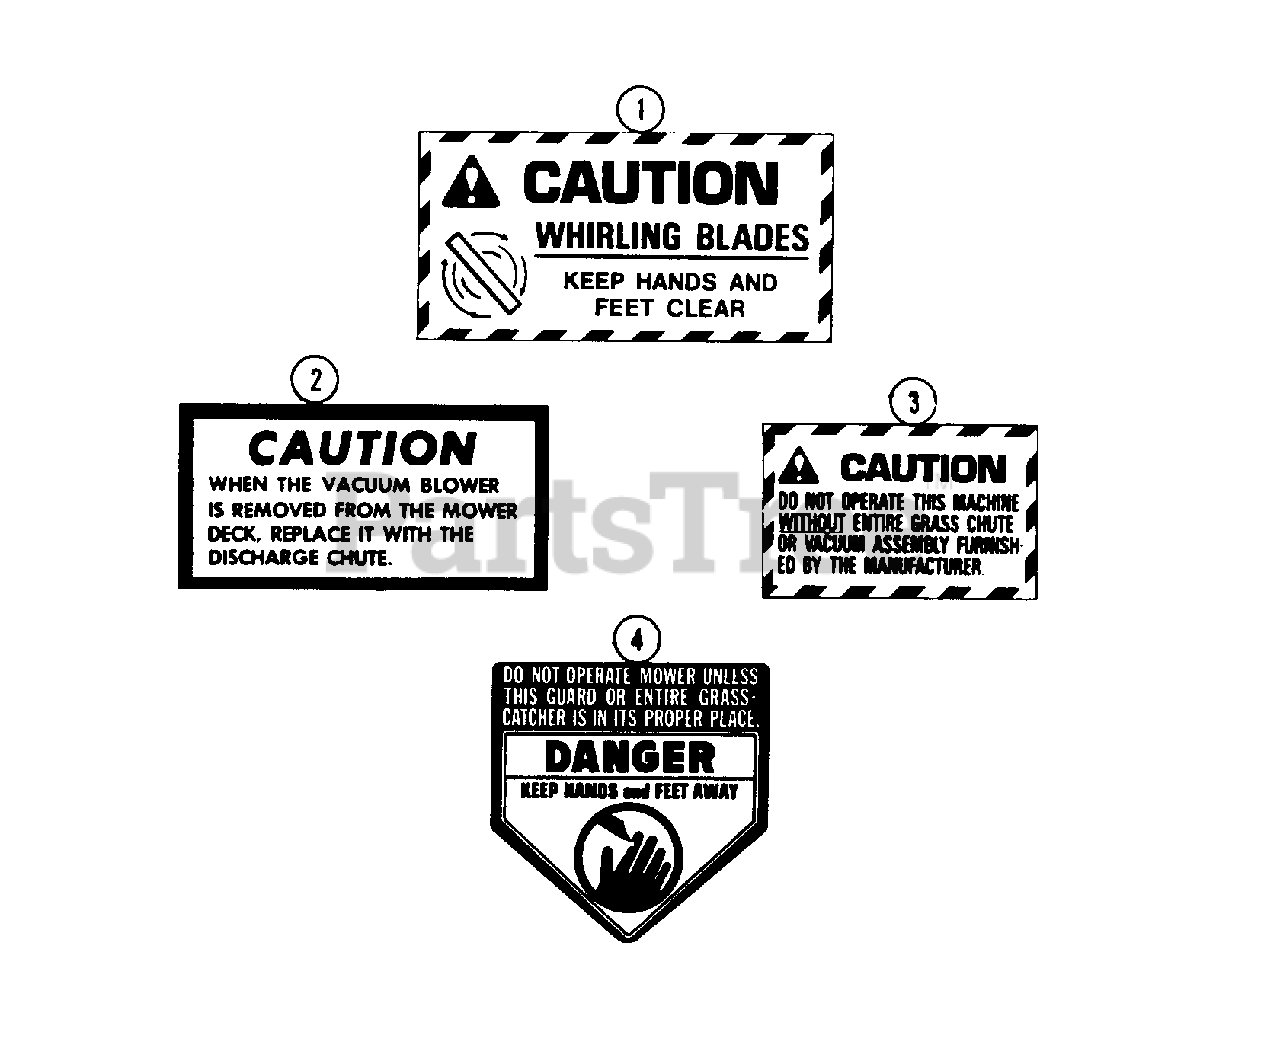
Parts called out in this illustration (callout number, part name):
1	DECAL - "Whirling Blades"
2	DECAL - "Caution" discharge chute
3	DECAL - "Caution" grass chute
4	DECAL - "Danger"
